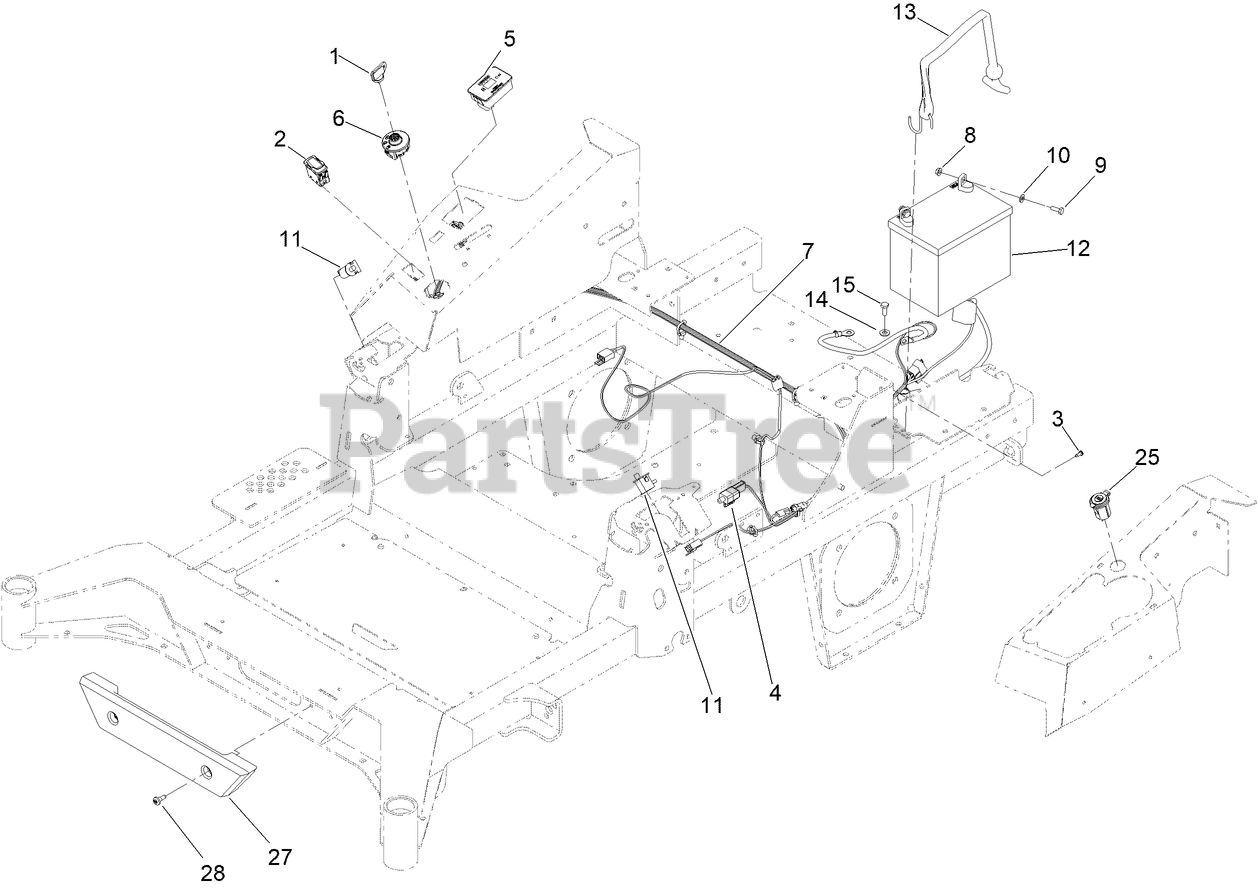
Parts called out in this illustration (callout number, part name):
1	KEYS-IGNITION (SPARE PAIR)
1	KEY-IGNITION
2	SWITCH-ROCKER, ON-NONE-ON
3	SCREW-HWH
4	SWITCH
5	MODULE ASM
6	SWITCH-IGNITION
7	HARNESS-WIRE
8	NUT-HF
9	SCREW-HH
10	WASHER-FLAT
11	SWITCH-BAIL
12	BATTERY-DRY
13	STRAP, BUNGEE
14	WASHER-PLAIN
15	SCREW-HH
25	PORT-POWER, USB
27	BUMPER-FRONT
28	SCREW-SHOULDER
